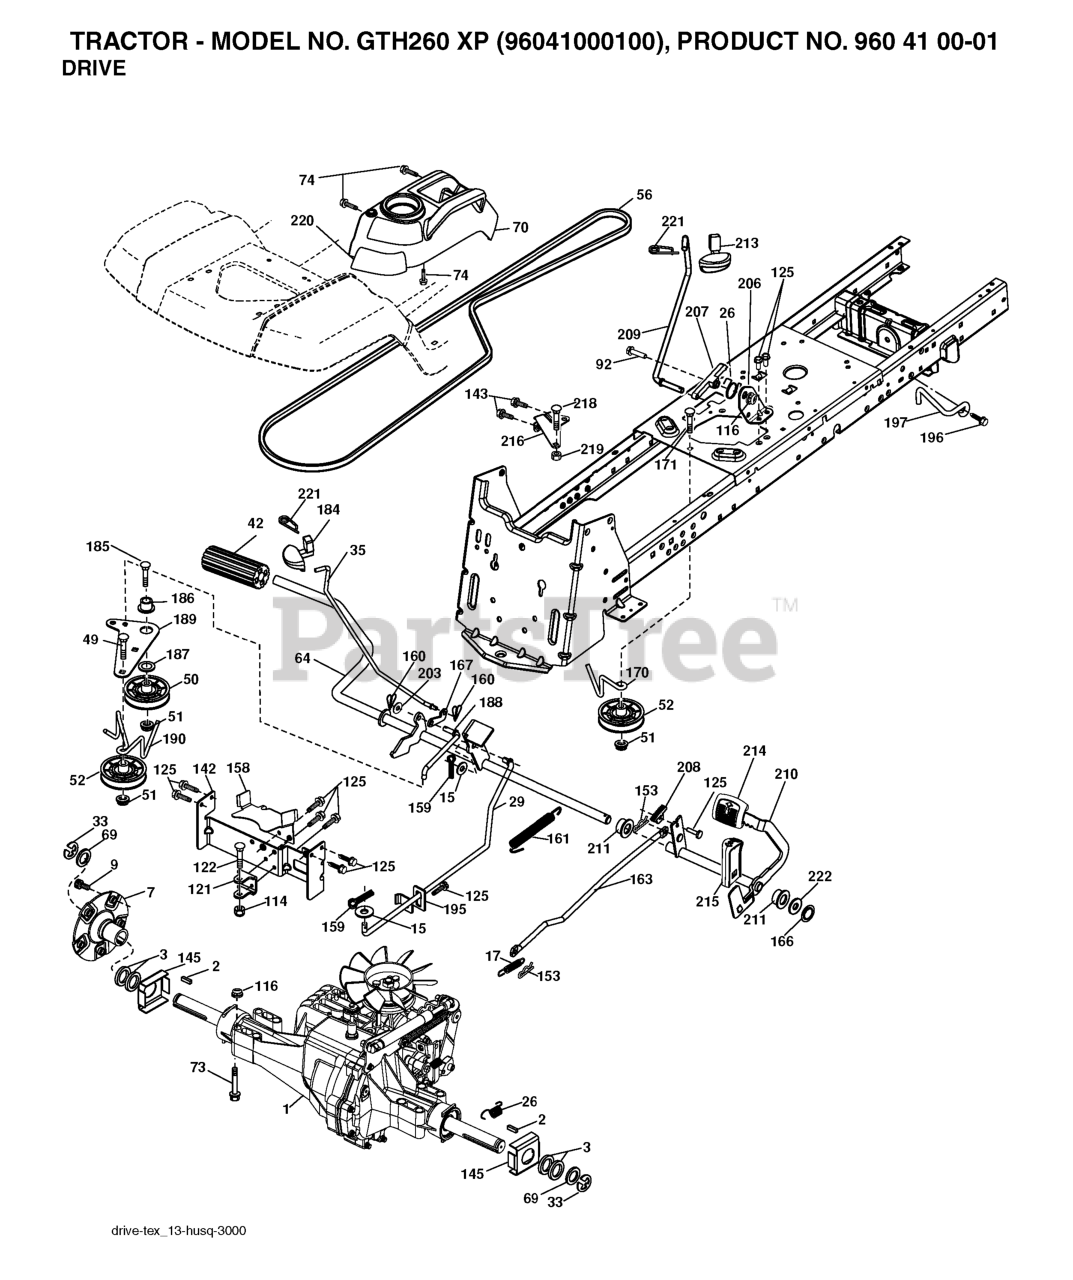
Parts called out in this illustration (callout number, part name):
2	KEY 1/4 X 2.5
7	HUB.ASM.WHEEL.REAR.23"TEX
9	HUB BOLT
15	WASHER
17	SPRING.BRAKE.HG3000/3500
26	SPRING.RETURN.CRUISE
29	ROD.BRAKE.HG3000/3500
33	E RING HYT
35	ROD.BRAKE.PARKING.GT.H
42	COVER, PEDAL (1 2)
50	IDLER.FLAT.910.OFFSET
51	NUT LOCK FLG 3/8-16 UNC
52	IDLER.V-GROOVE.910.OFFSET
56	BELT.V.GROUND.DRIVE
64	SHAFT.ASM.PEDAL.BRK.CNTR
70	RP CONSOLE.ASM.PCH.W/TB
73	BOLT HEX FLGHD 5/16-18X3 GR. 5
74	SCREW.HI-LO.CONSOLE
92	BOLT
114	NUT.71038.31-18.HEX.NYLOCK
116	NUT LOCK HEX FLANGE 5/16-18
121	BRACKET STRAP TORQUE
122	BOLT.5/16-18X2.5
125	SCREW
142	STRAP.TORQUE.HG300/3500
143	Screw 5/16-18 x 1/2 Hex, Self Tapping 5/16-18 x 1/2
145	WASHER.AXLE.FLANGE.HG-3000
148	SCREW, 3/8-16X3/4
153	RETAINER M
158	KEEPER BELT
159	COTTER PIN
160	RETAINER CLIP
161	SPRING.RETURN.CLUTCH.2006
166	NUT.PUSH.625.2006
167	LATCH.BRAKE.SPRING
170	KEEPER.V-IDLER.CENTER.
171	BOLT
184	HANDLE.PARKG.BRK.HUSQ X667
185	BOLT
186	SPACER.RETAINER
187	WASHER 12/32X2X10GA
188	RP.LINK.CLUTCH.GROUND.DRIVE
189	BELLCRANK.GROUND.DRIVE.TEX.
190	KEEPER.BELLCRANK.DRIVE
196	SCREW 3/8-16X1
197	BRKT.ANIT-ROTATION.CLUTCH
203	WASHER
206	BRKT.MOUNT.LATCH.CRUIS
207	LATCH.CONTROL.CRUISE
208	GEAR.SECTOR.CONTROL.CR
209	ROD.CONTROL.CRUISE.GT.
210	ROCKER.ASM.PEDAL.CONTR
211	BEARING.NYLON
213	KNOB.CONTROL.CRUSIE.HU
214	PEDAL.FORWARD.TEX.GT.4
215	PEDAL.REVERSE.TEX.GT.4
216	BRACKET.PULLEY.IDLER.W/TEX
218	BOLT.5/16-18X1-1/4 FULL.THREAD
219	SPACER.FENDER
220	REFLECTOR.RH.TEX GT
221	RETAINER.SPRING.CLIP.H
222	WASHER
223	BOLT
